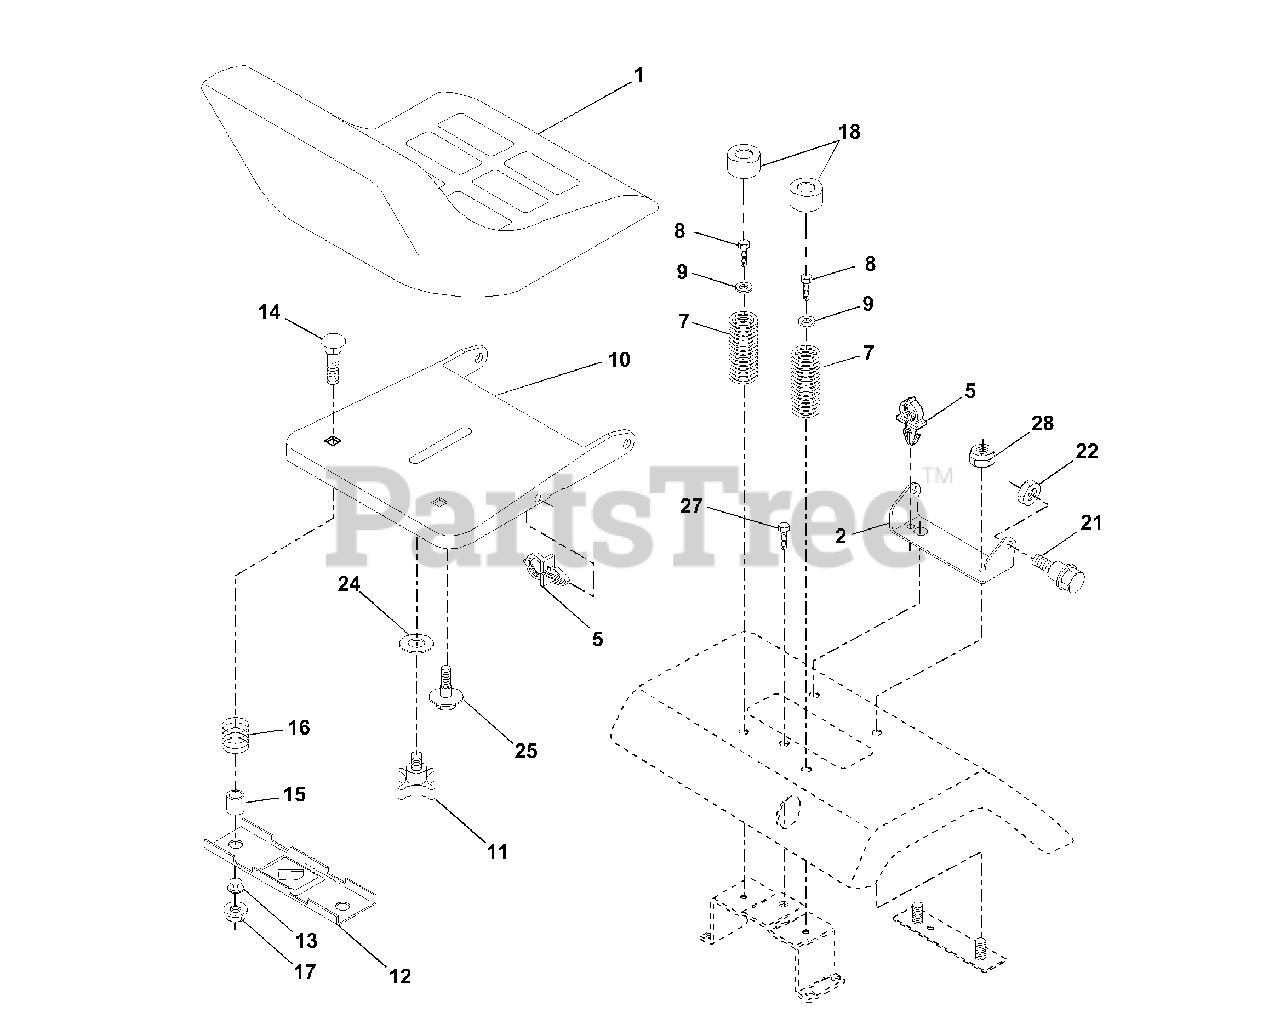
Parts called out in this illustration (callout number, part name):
1	Seat V-550 Gry/blk Std
2	Bracket Pivot Seat
5	Clip, Push-In Hinged
7	Spring Seat Cprsn 2 250 Blk Zi
8	Screw Hwsh Thdrol 5/16-18 x 1/2
9	Washer 13/32 X 1 X 14 Ga
10	Pan Seat
11	Knob Seat 1/2-13unc Blk
12	Bracket Mounting Switch
13	Bushing Snap Blk Nyl 50 Id
14	Bolt Rdhd Sht Nk 1/4-20x1-3/8
15	Spacer Split 28x 88 Yel Zinc
16	Spring Cprsn 1 310 Blk Pnt
17	Nut Lock 1/4 Lge Flg Gr 5 Zinc
18	Cap Spring Seat
21	Bolt Shoulder 5/16-18 Unc Blkz
22	Nut Crown Lock 5/16-18
24	Washer 17/32 X 1-3/16 X 12 Ga
25	Bolt Shoulder 5/16-18 X 62
27	Screw Thdrol 3/8-36 x 1/2
28	Nut Crownlock 3/8-16 UNC
